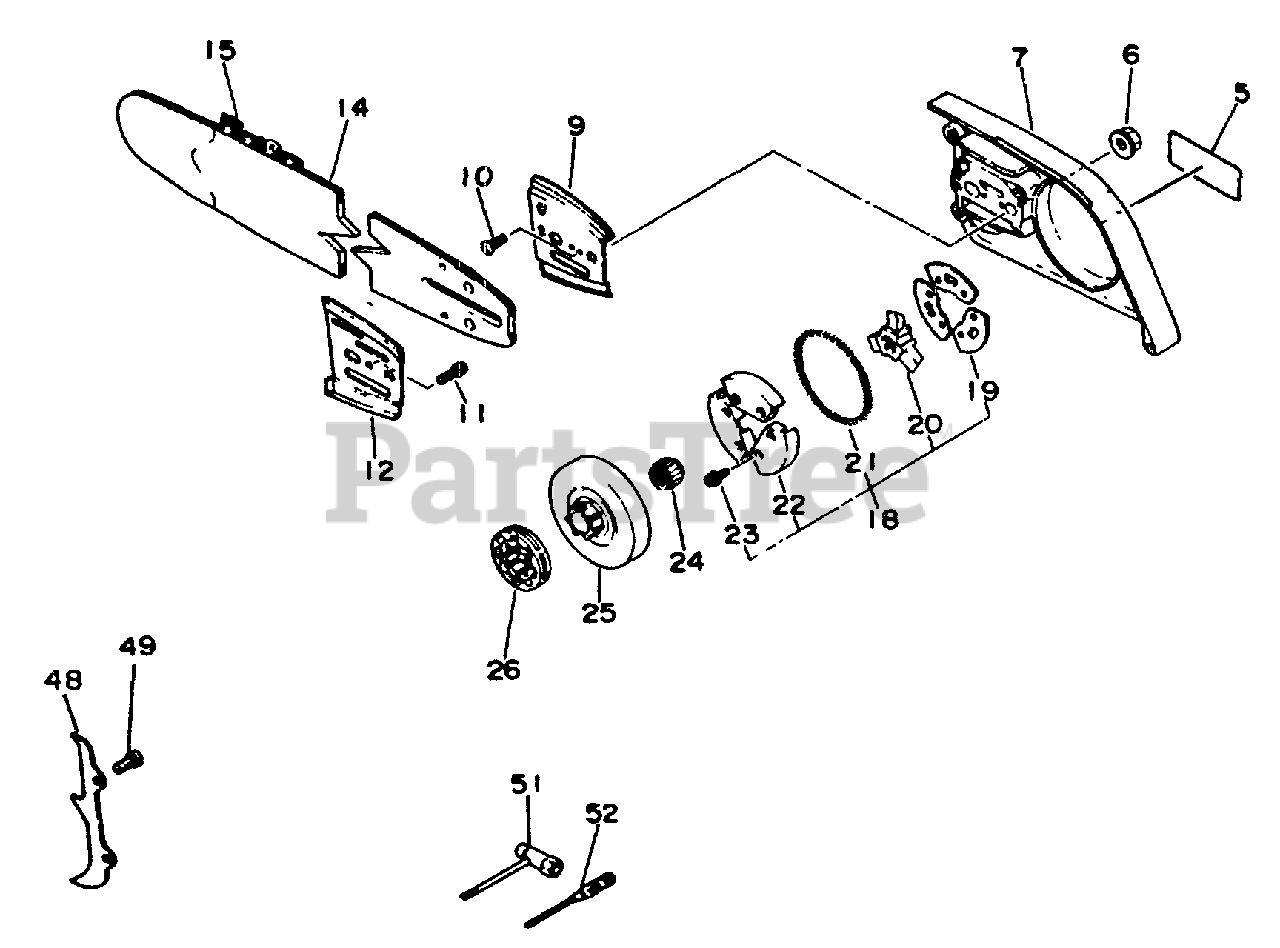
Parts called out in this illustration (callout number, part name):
5	LABEL - ECHO
6	NUT - FLANGE
7	GUARD, SPROCKET
9	PLATE, GUIDE - OUTER
10	SCREW - 3X6
11	SCREW - 4X10
12	PLATE, GUIDE - INNER
14	GUIDE BAR
15	CHAIN, SAW
18	CLUTCH ASSY
19	PLATE, CLUTCH
20	HUB, CLUTCH
21	SPRING, CLUTCH
22	CLUTCH SHOE SET
23	SCREW - 4X8
24	BEARING, NEEDLE
25	DRUM, CLUTCH
26	SPROCKET, RIM
48	SPIKE
51	T-WRENCH - 13X19mm
52	SCREWDRIVER
